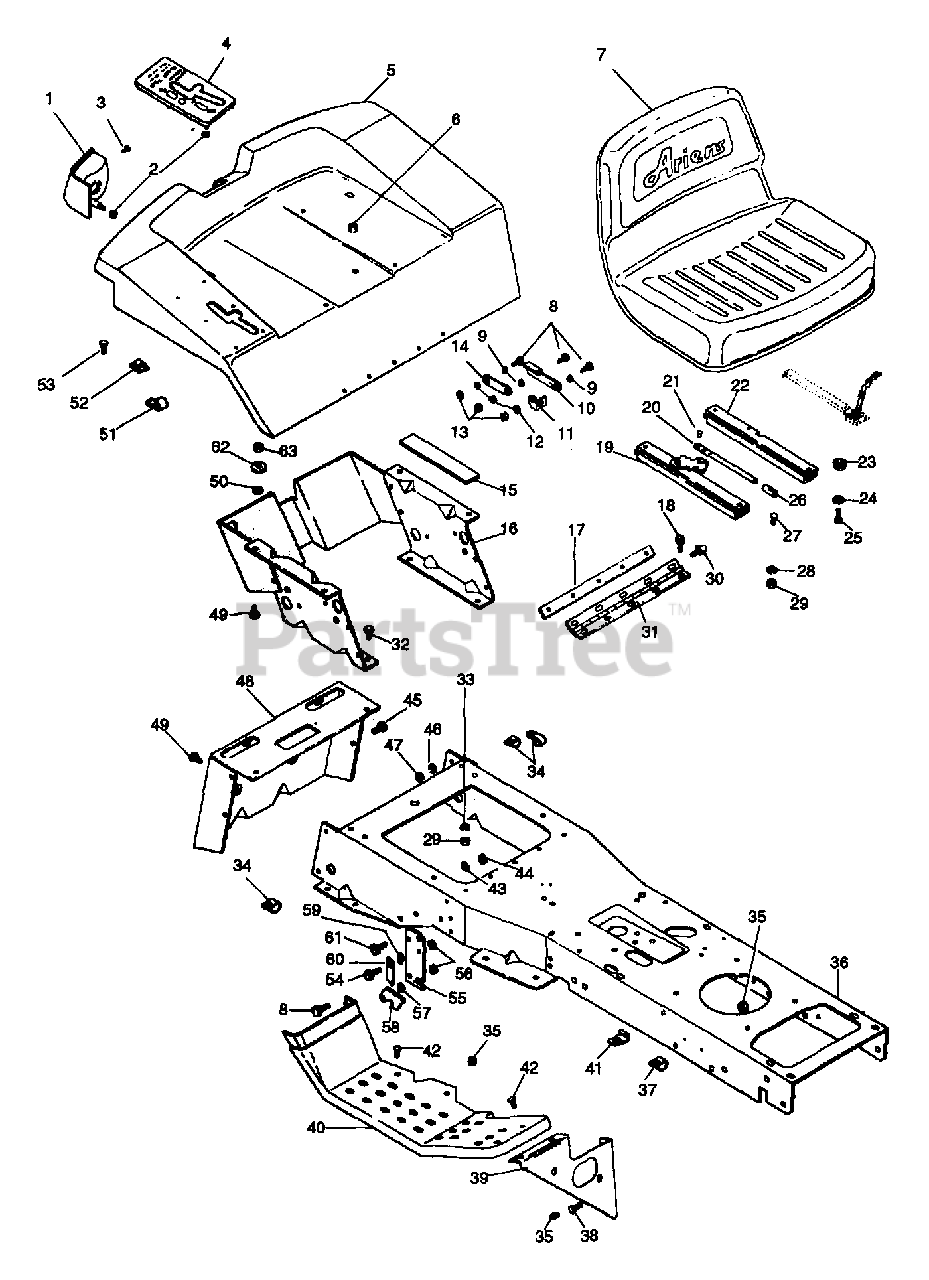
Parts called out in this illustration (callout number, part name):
1	RIGHT TAIL LIGHT
2	NUT-SELF-THRDNG FITS.25 STUDPL
3	SCR-TAP 10-12X.50 CRPH PL A
5	REAR DECK
6	GROMMET
7	SEAT
8	BLT-HEX .25-20X.63 PL GR2
9	SPACER .272X.438X.145
10	DECK PROP
11	BRACKET
12	WSHR-FL-STL.281X.62X.065 PL
13	NUT-LK-CTR .250-20 PL
14	STRAP
15	FOAM TAPE
16	DECK SUPPORT
17	STRAP
18	SCR-TAP .312-18X.75 HWH PL TR
19	SEAT SLIDE R H
20	SEAT SLIDE HANDLE
21	RVT-POP.187X.562 DOME ST
22	SEAT SLIDE L H
23	SEAT SLIDE SPACER
24	WSHR-LK-EXT .313X.030 PL
25	SCR-MCH .31-18X1.00 CRRH PL
27	SCR-CAP BTHD.31-18X.50 GR5 YZ
28	WSHR-LK .313X.078 PL MED
29	NUT-HEX .312-18
30	SCR-TAP .312-18X.50 HWH PL TR
31	HINGE-2" X 12.88 YWZC
32	BLT-HEX .31-18X.75 PL GR5
33	WSHR-LK .312X.097 PL HVY
34	J-CLAMP
35	NUT-FLG. .312-18 PL
36	MAIN FRAME
37	J-CLAMP
38	BLT-RDHDSQNK .31-18X.75 SHT PL
39	R H FOOTREST BRACE
40	FOOT REST R H
42	BLT-RDHDSQNK .31-18X.75 GR5 PL
43	WSHR-LK .250X.077 HVY PL
44	NUT-HEX .250-20 PL
45	BLT-HEX .38-16X1.00 PL GR5
46	WSHR-LK .375X.115 HVY PL
47	NUT-HEX .375-16
48	TAILBOARD
49	HANDLEBAR STUD
50	NUT-LK-JAM-CTR .375-16 PL
51	J-CLIP
52	WIRE CLIP
53	SCR-CAP BTHD.31-18X.875 GR5 PK
54	BLT-HEX .38-16X1.50 PL GR5
55	REAR HANGER
56	NUT-LK TOP .375-16 GR C YWZC
57	SPRING WASHER
58	LATCH RH
59	SPACER .400X.625X.400X.875
60	LOCK STOP
61	BLT-HEX .31-18X1.00 PL GR 2
62	WSHR-FL-STL .343X1.370X.145 PL
63	NUT-HEX .312-18
